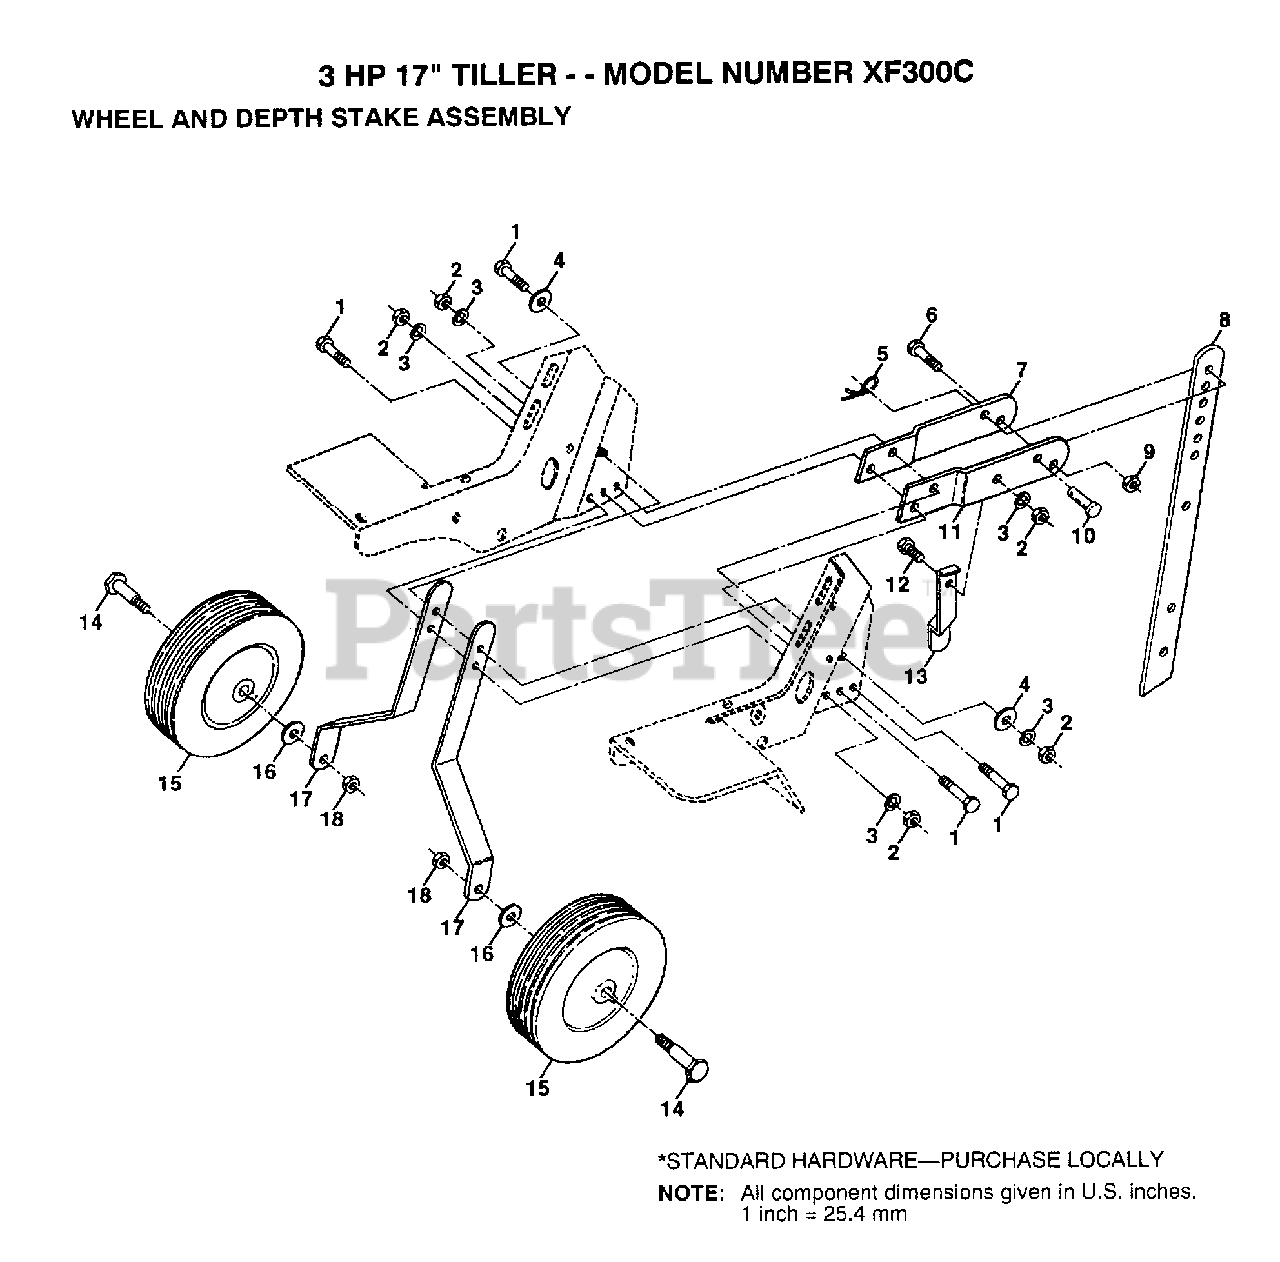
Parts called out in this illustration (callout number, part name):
2	NUT.HEX.5/16-18
3	LOCKWASHER
4	WASHER
5	SPRING.RETAINER
6	BOLT.3/8-24X1-1/2
7	STAKE.SUPT.TILLER
9	GRIPCO NUT
10	DRILLED RIVET RT
12	BOLT
13	STAKE SPRING CT
14	BOLT SHOULDER
16	WASHER
